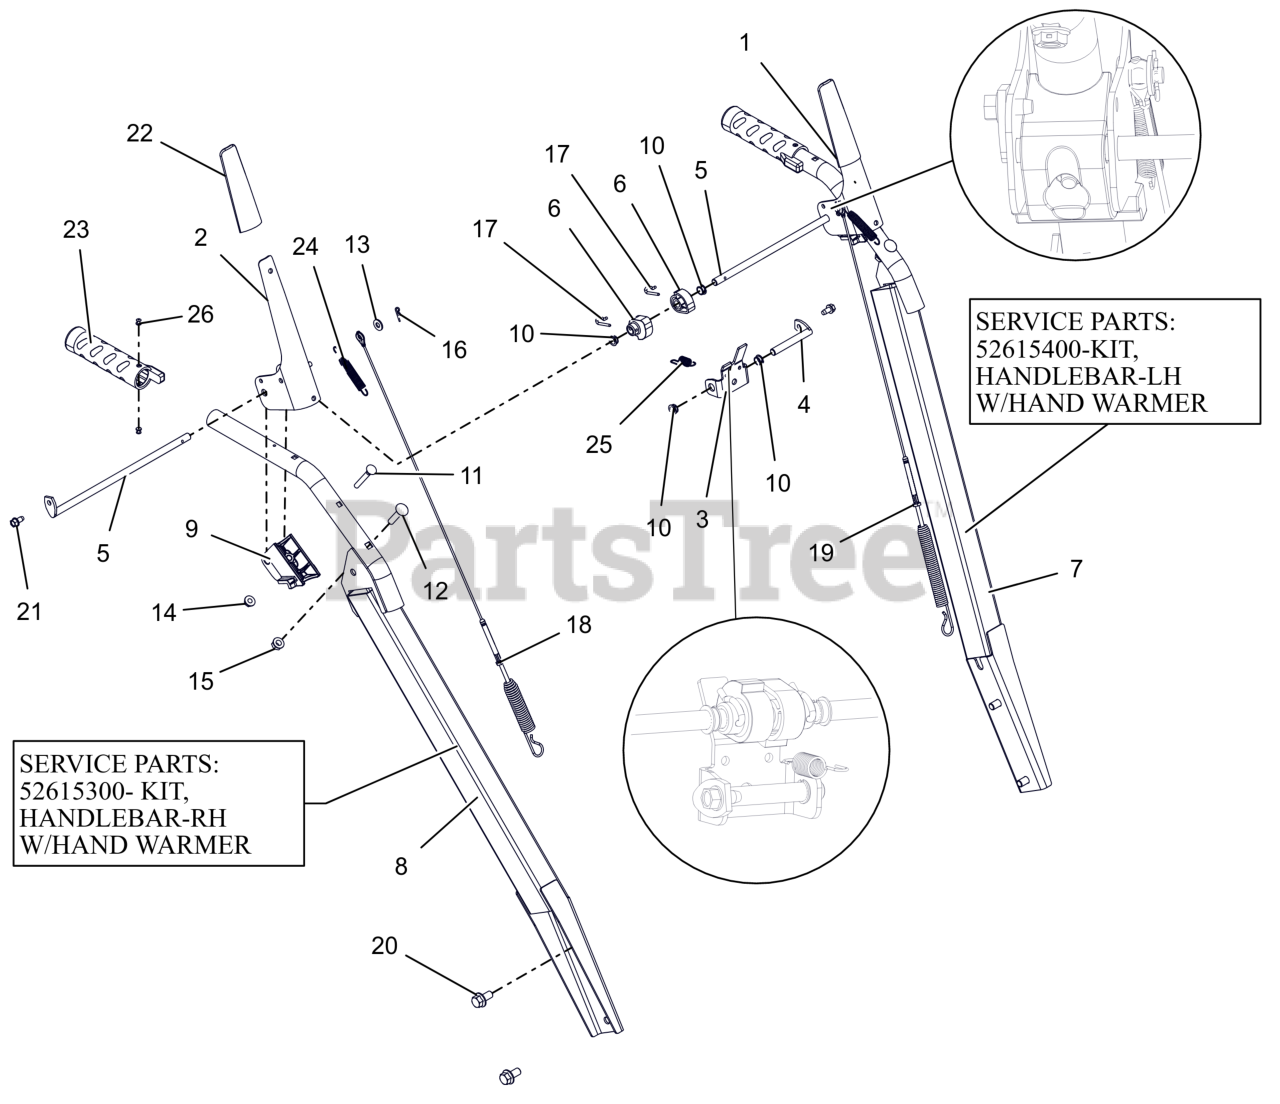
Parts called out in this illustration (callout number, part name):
1	LEVER, CLUTCH-LH
2	LEVER, CLUTCH-RH
3	BRACKET, INTERLOCK ARM
4	ROD, PIVOT - INTERLOCK
5	ROD, PADDLE MOUNT - PRO
6	CAM, INTERLOCK
7	HANDLEBAR, HEAVYDUTY-PRO LH
7	KIT, HANDLEBAR-LH W/WARM GRIP
8	HANDLEBAR, HEAVYDUTY-PRO-RH
8	KIT, HANDLEBAR-RH W/WARM GRIP
9	BLOCK, CLUTCH PADDLE
10	BUSHING, POLYLINER-.38 SNAPIN
11	BLT-RDHDXLSQNK .25-20X2.0 G5YZ
12	BLT,RHSN .31-18X1.50 G5 ZCC
13	WSHR,FLT .281X.625X.065 ZCC
14	NUT-LK-CTR-FLG .25-20 ZC120
15	NUT-LK-TOP-FLG .312-18 GF ZCC
16	PIN, HAIR #178 .06X.77 ZCC
17	PIN, SPRING CLIP
18	CABLE, AUGER (DELUXE & PRO)
19	CABLE, UPPER TRACTION
21	SCR-TAP .25-20X.50 HWH ZCC
22	SLEEVE, CLUTCH PADDLE-GRAY
23	GRIP,HEATED HANDLE-GRAY
24	SPRING, EXTENSION
25	SPRING-EXT .047X.438X1.45
26	RVT-POP #43 .125X.313 STL ZINC
